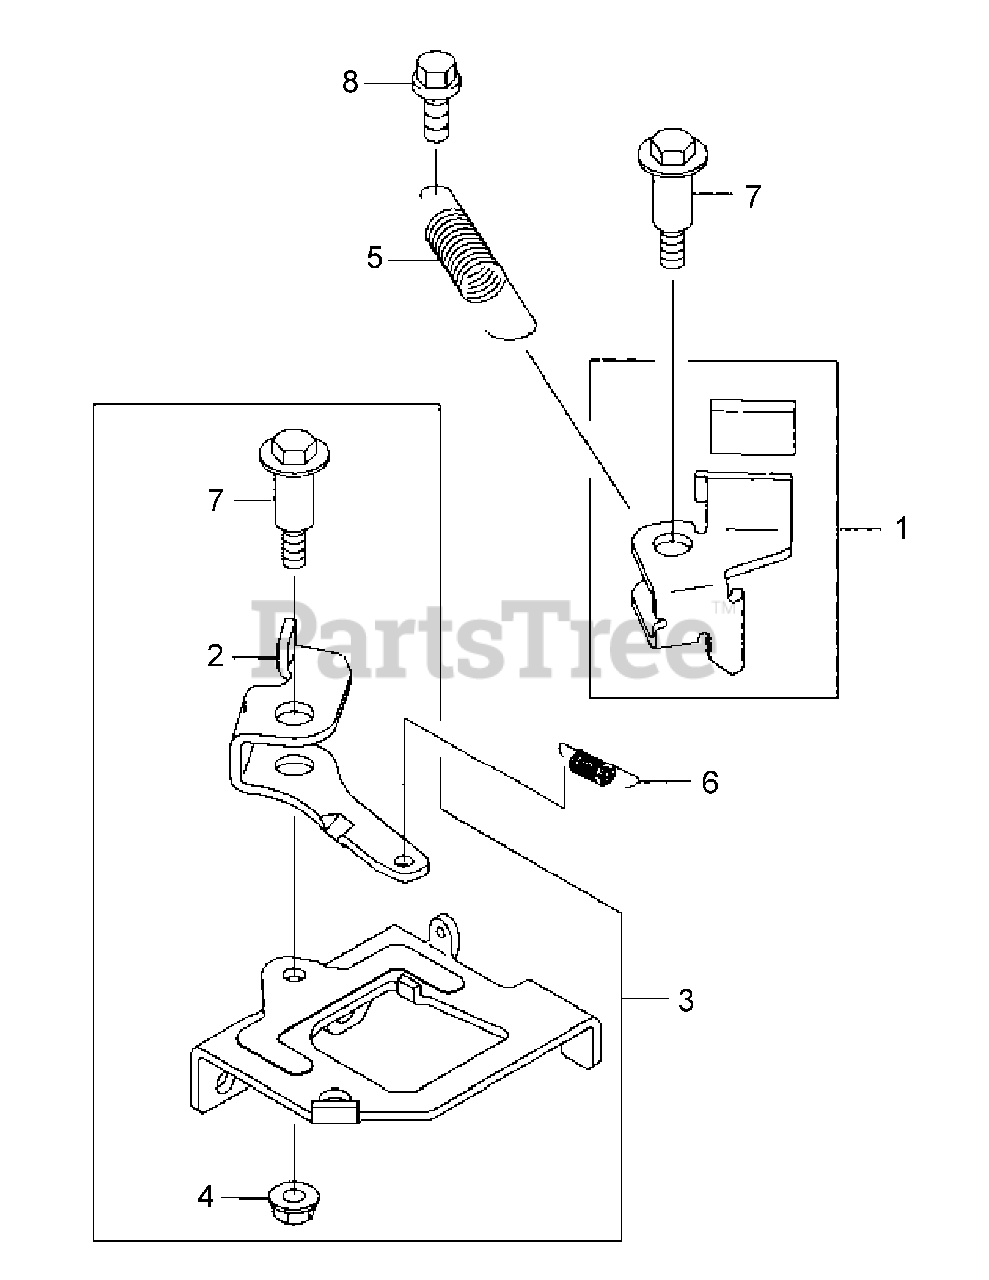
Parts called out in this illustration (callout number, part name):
1	Lever
3	Brake Panel Assy.
4	Nut
6	Spring
8	Flanged Bolt
